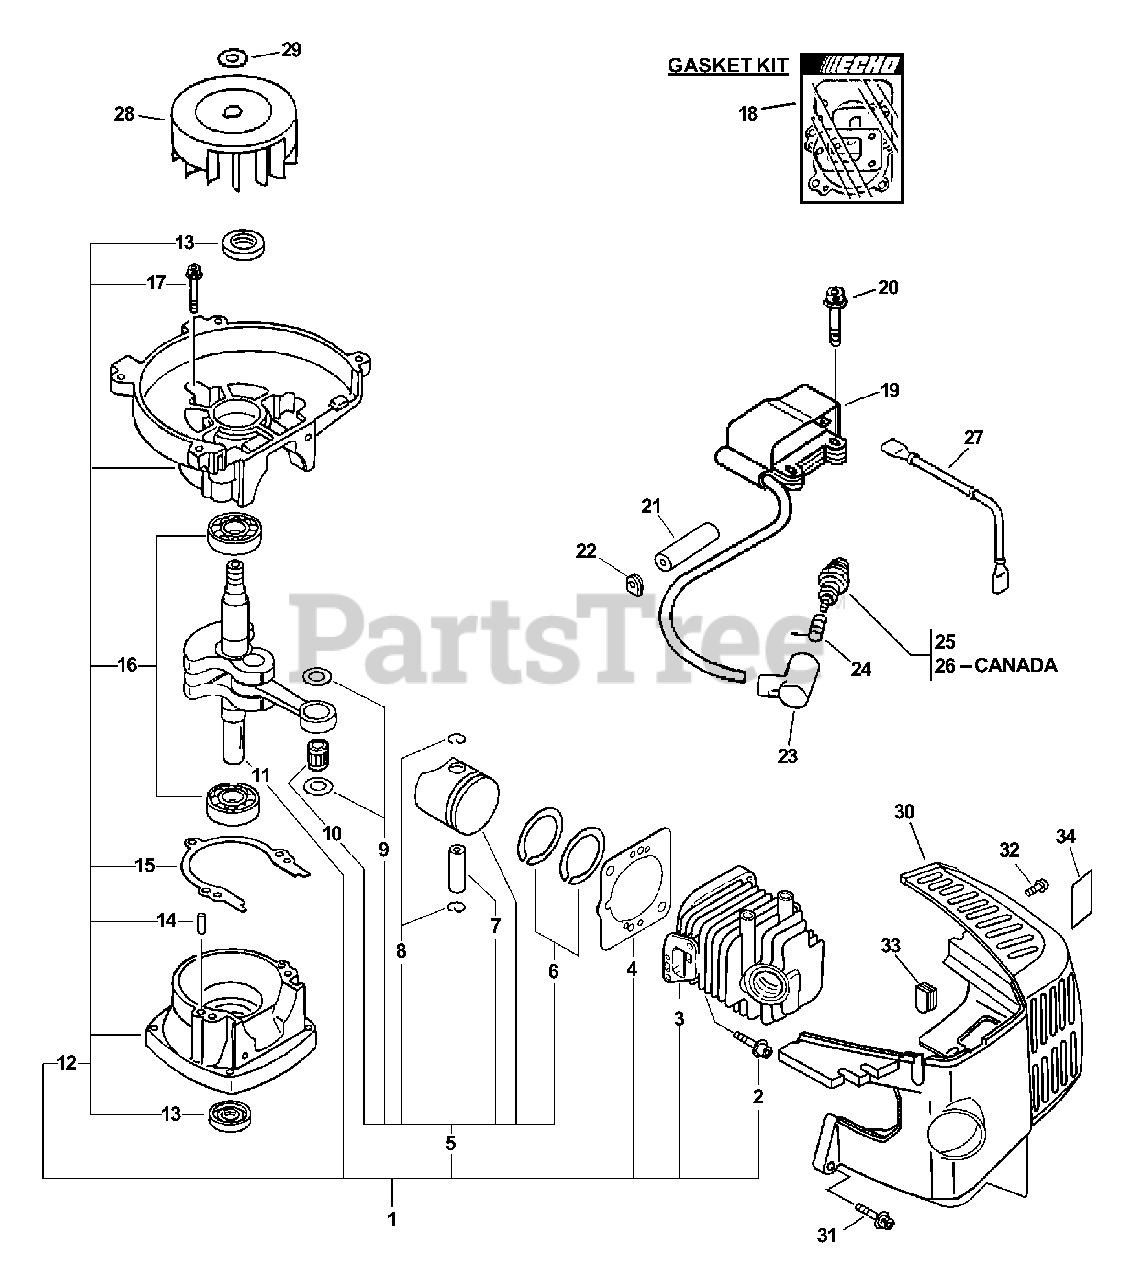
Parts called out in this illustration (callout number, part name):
1	SHORT BLOCK
2	SCREW 4×22
3	CYLINDER
4	GASKET, CYLINDER
5	PISTON KIT
6	RING, PISTON
7	PIN, PISTON 8
8	RING, SNAP
9	WASHER, THRUST
10	BEARING, NEEDLE
11	CRANKSHAFT ASSY
12	CRANKCASE KIT
13	SEAL, OIL 12
14	PIN, LOCATING 4
15	GASKET, CRANKCASE
16	BEARING, BALL - 6201 C3
17	BOLT 5×28
18	GASKET KIT
19	COIL, IGNITION
20	BOLT 4×20
21	TUBE, INSULATOR
23	CAP, SPARK PLUG
24	TERMINAL, SPARK PLUG
25	SPARK PLUG - BPM8Y
26	SPARK PLUG - BPMR8Y
27	LEAD - IGNITION
28	WASHER 8.5×16×1.2
29	FLYWHEEL
30	COVER, ENGINE
31	BOLT 5×22
32	BOLT 4×8
33	PLUG
34	LABEL, CAUTION - HOT
